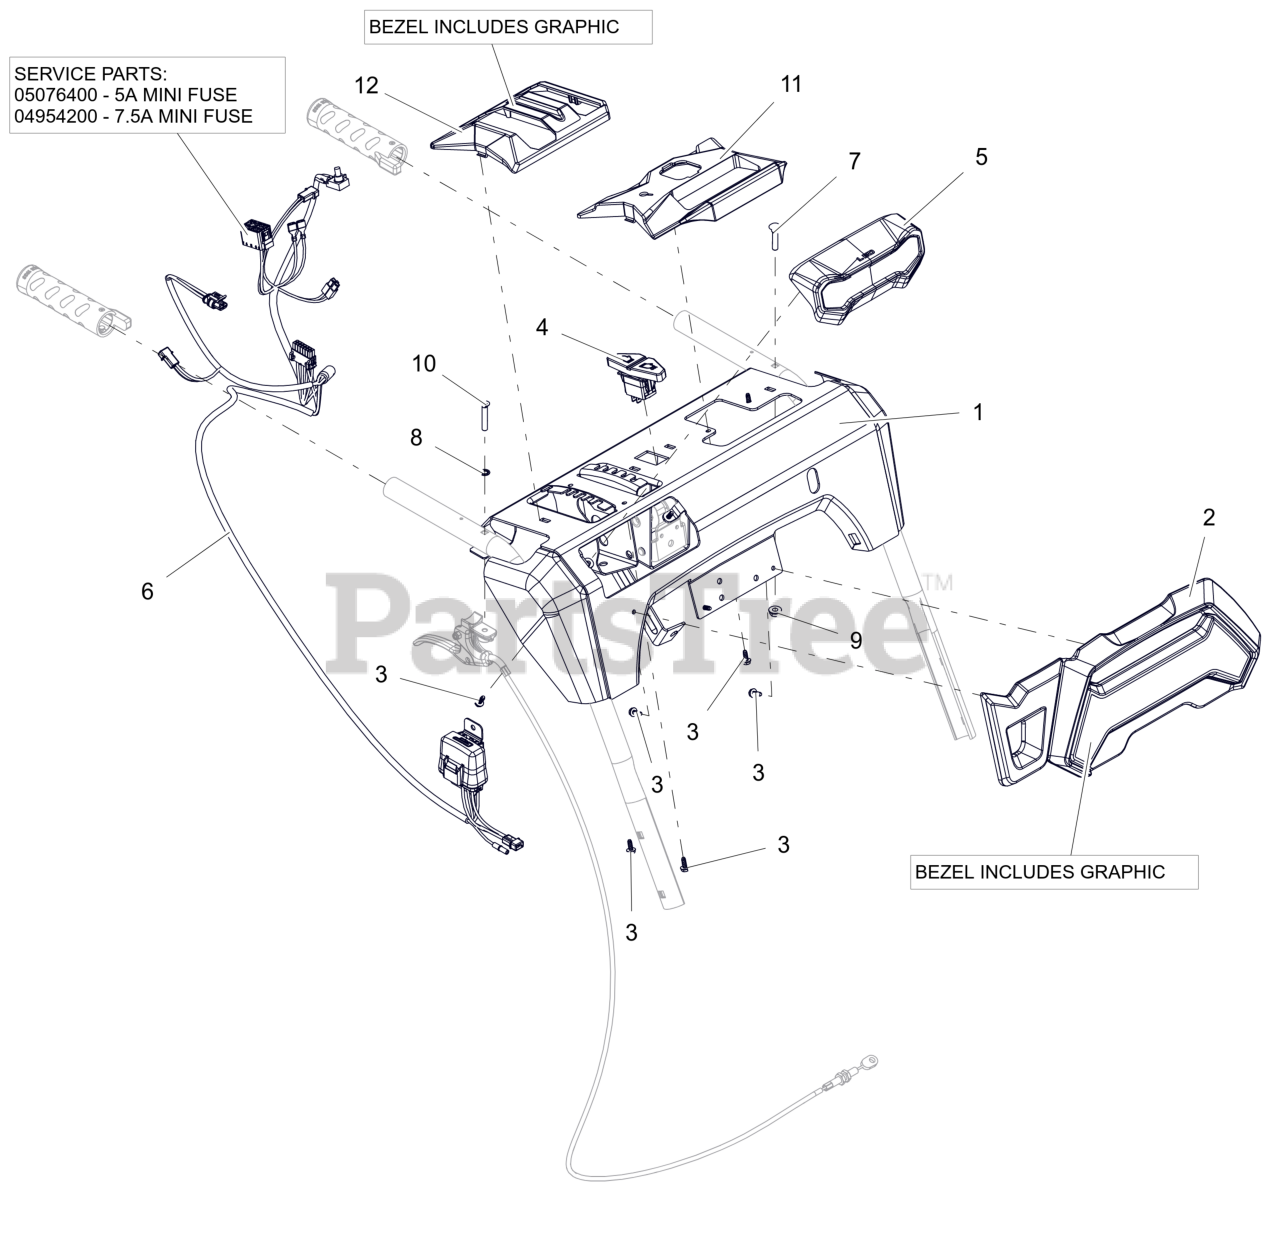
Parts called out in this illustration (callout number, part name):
1	PANEL, CONTROL-EFI ID W/DECAL
2	BEZEL- LARGE - PLATINUM
3	SCR, PLASTIC #10X.50
4	SWITCH- ROCKER SPST-ON/OFF
5	HEADLIGHT ASM- LED
6	HARNESS- WIRE - LT HG EFI
6	FUSE, 5 AMP MINI-ATC
6	FUSE, 7.5 AMP MINI-ATC
7	BLT-RDHDXLSQNK.25-20X1.25 G5ZC
8	WSHR-LK-INT .250 TH TYA
9	NUT-LK-CTR-FLG .25-20 ZC120
10	SCR,OVAL .25-20X1.50 ZCC
11	BEZEL, OPERATOR EFI CHUTE DECAL
12	BEZEL, SHIFT FRICT RT W/SAFTEY
